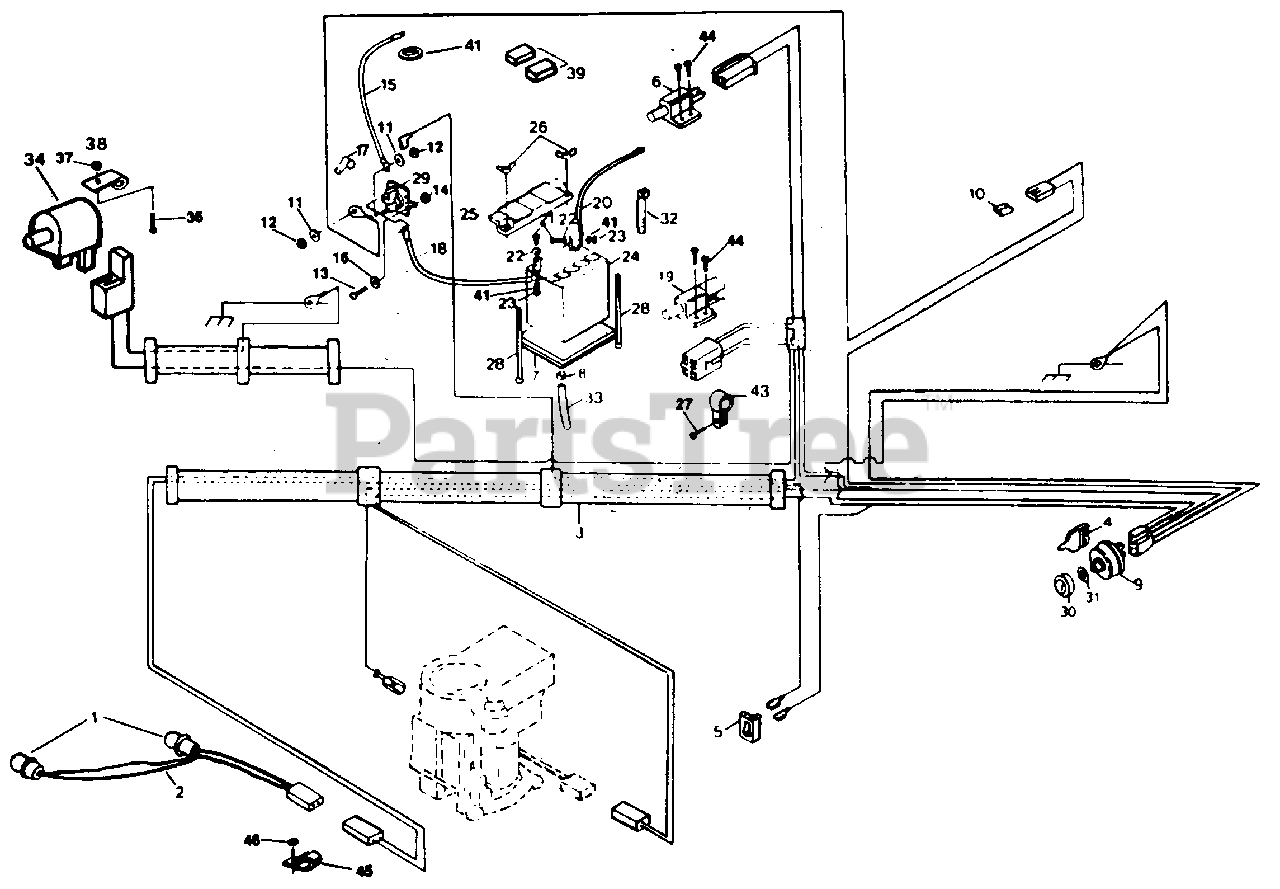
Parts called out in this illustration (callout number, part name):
1	Light Bulb (AYP part number)
2	Light Socket Harness (AYP part number)
3	Ignition Harness (AYP part number)
4	Molded Key (AYP part number)
5	Light Switch (AYP part number)
6	Interlock Switch (AYP part number)
7	Battery Tray (AYP part number)
8	Hose Clamp (AYP part number)
9	Ignition Switch (AYP part number)
10	30 Amp Fuse (AYP part number)
11	Lock Washer 1/4 (AYP part number)
12	Hex Jam Nut 1/4-20 (AYP part number)
13	Hex Bolt 1/4-20 x 1/2 Gr. 5 (AYP part number)
14	Keps Nut (AYP part number)
15	Ground Cable (AYP part number)
16	Ext. Tooth Lock Washer (AYP part number)
17	Terminal Cover (AYP part number)
18	Battery Cable (AYP part number)
19	Interlock Switch (AYP part number)
20	Battery Cable (AYP part number)
21	Hex Bolt 1/4-20 x 3/4 (AYP part number)
22	Washer 9/32 x 5/8 x 16 Ga. (AYP part number)
23	Hex Nut 1/4-20 (AYP part number)
24	Battery (AYP part number)
25	Terminal Guard (AYP part number)
26	Wing Nut 1/4-20 (AYP part number)
27	Washer Head Hex Screw (AYP part number)
28	Sq. Nk. Rd. Hd. Bolt (AYP part number)
29	Solcnoid (AYP part number)
30	Ignition Bezel (AYP part number)
31	Ignition Nut (AYP part number)
32	Cable Ti?? (AYP part number)
33	Plastic Tube (AYP part number)
34	Plunger Switch (AYP part number)
36	Slotted Pan Hd. Screw (AYP part number)
37	Keps Nut (AYP part number)
38	Insulated Clip (AYP part number)
39	Battery Caps Set (AYP part number)
41	Lock Washer (AYP part number)
43	Insulated Clip (AYP part number)
44	Hex Screw (AYP part number)
45	Fuel Line Clip (AYP part number)
46	Crown Lock Nut
